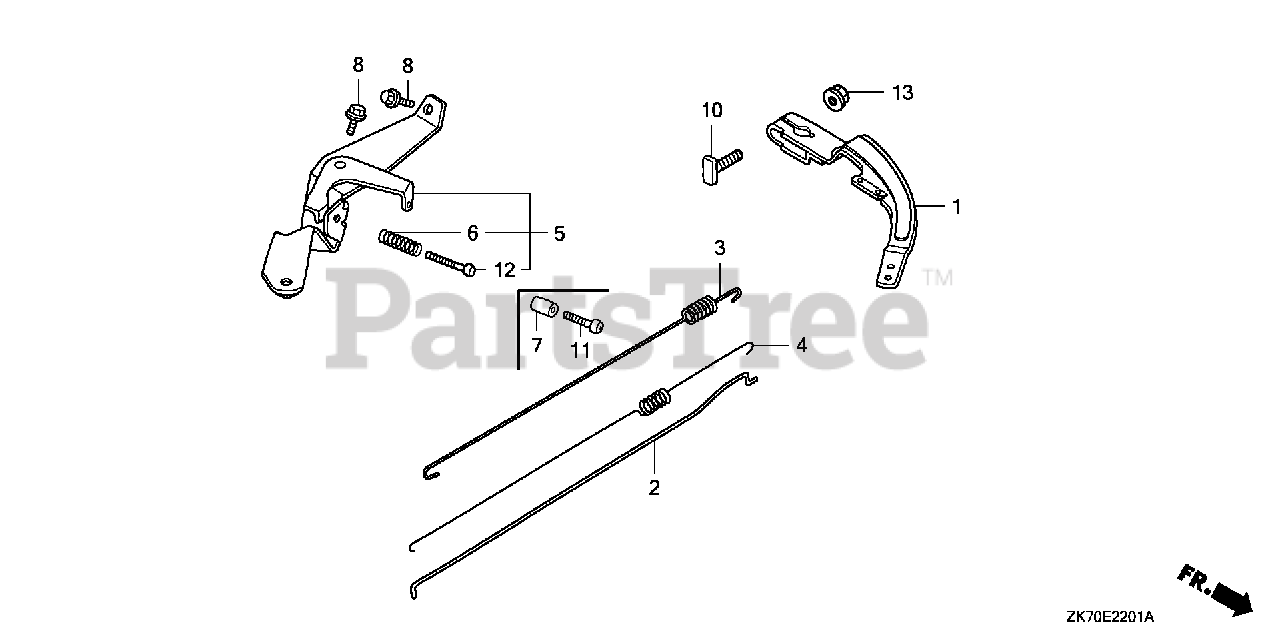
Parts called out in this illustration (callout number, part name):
1	ARM, GOVERNOR
2	ROD, GOVERNOR
3	SPRING, GOVERNOR
4	SPRING, THROTTLE RETURN
5	CONTROL ASSY.
6	SPRING, CONTROL ADJUSTING
7	COLLAR, STOPPER
8	BOLT, FLANGE (6X12) (CT200)
10	BOLT, GOVERNOR ARM
11	SCREW, RECESSED (5X25)
12	SCREW, PAN (5X35)
13	NUT, FLANGE (6MM)
